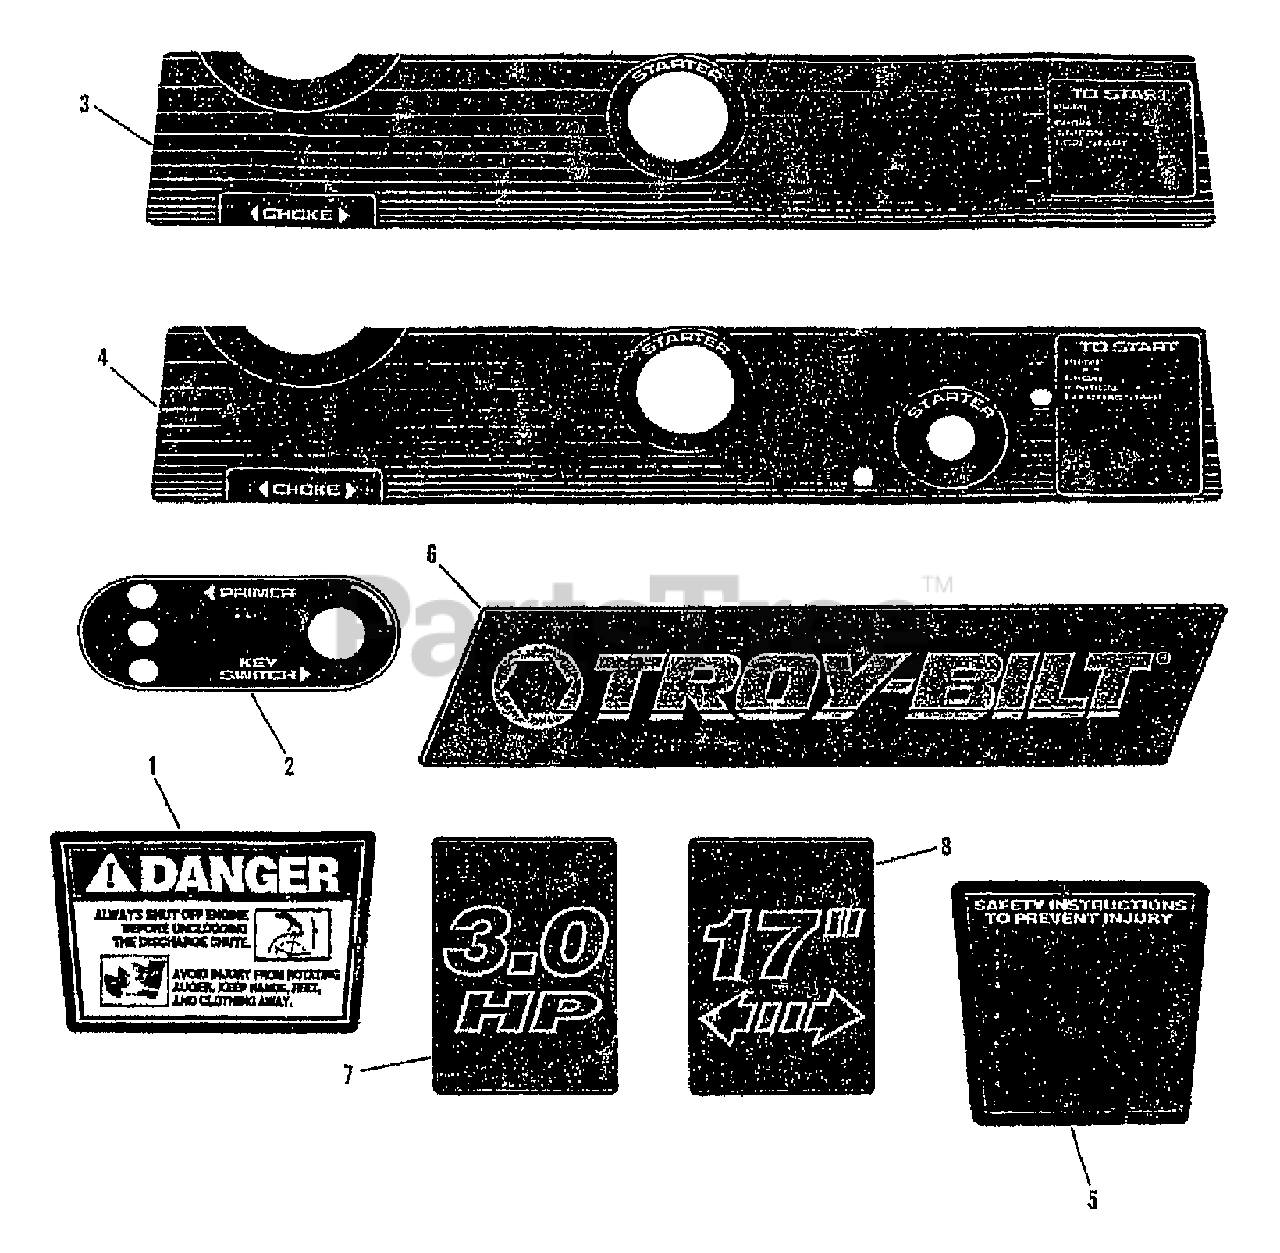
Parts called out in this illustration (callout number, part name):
1	DECAL-DANGER
2	DECAL-PRIMER INST
3	DECAL-PANEL INST STD MDL
4	DECAL-PANEL INST ELEC MDL
5	DECAL-SAFETY INST
6	DECAL-LOGO SIDE CVR T/B
7	DECAL-3HP SNOWTHROWER
8	DECAL
